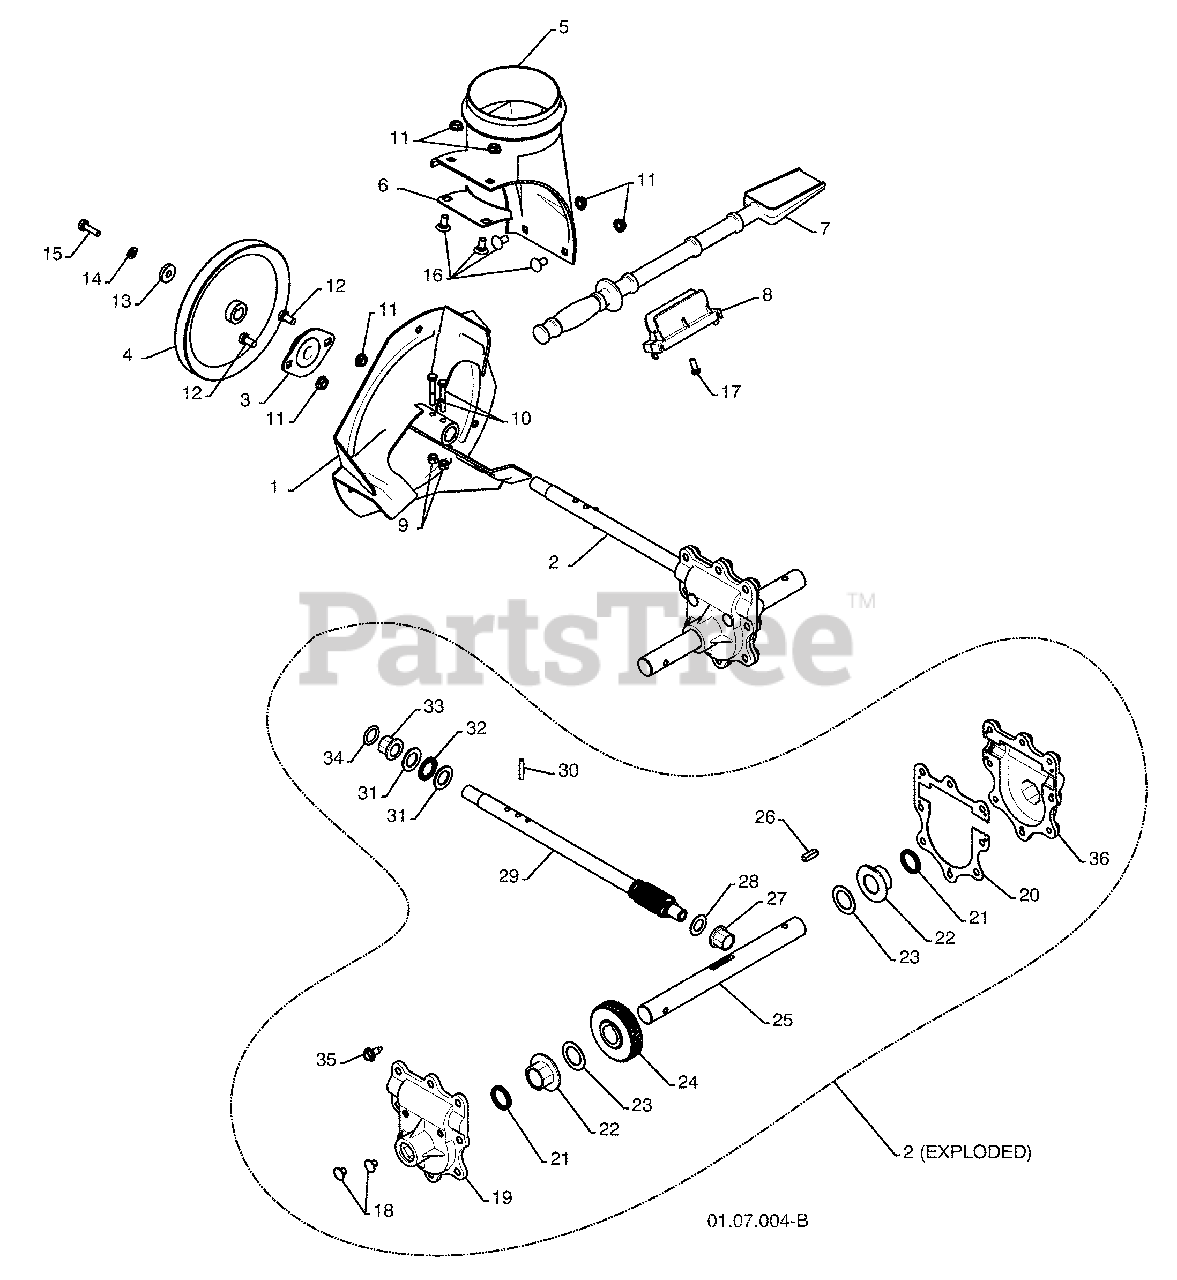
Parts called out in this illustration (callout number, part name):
1	IMPELLER
2	GEARBOX ASSEMBLY
4	IMPELLER PULLEY
5	DISCHARGE BASE
6	CORNER BRACKET
7	CLEAN OUT TOOL
9	NUT 1/4-20
10	SCREW 1/4-20 X .625
11	NUT 5/16-18
12	SCREW 5/16-18 X .625
14	LOCKWASHER 5/16
15	SCREW 5/16-18 X 1.00
16	CARRIAGE BOLT
17	SCREW 13-16 X .625
18	PLUG
19	GEARBOX COVER RH
20	GASKET
21	SEAL
22	BEARING
23	THRUST WASHER 1.00
24	WORM GEAR
25	AUGER SHAFT
26	SQUARE KEY
27	BEARING
28	THRUST WASHER
29	IMPELLER SHAFT
30	ROLL PIN
31	THRUST WASHER
32	THRUST BEARING
35	SCREW 5/16-18 X .750
36	GEARBOX COVER LH
